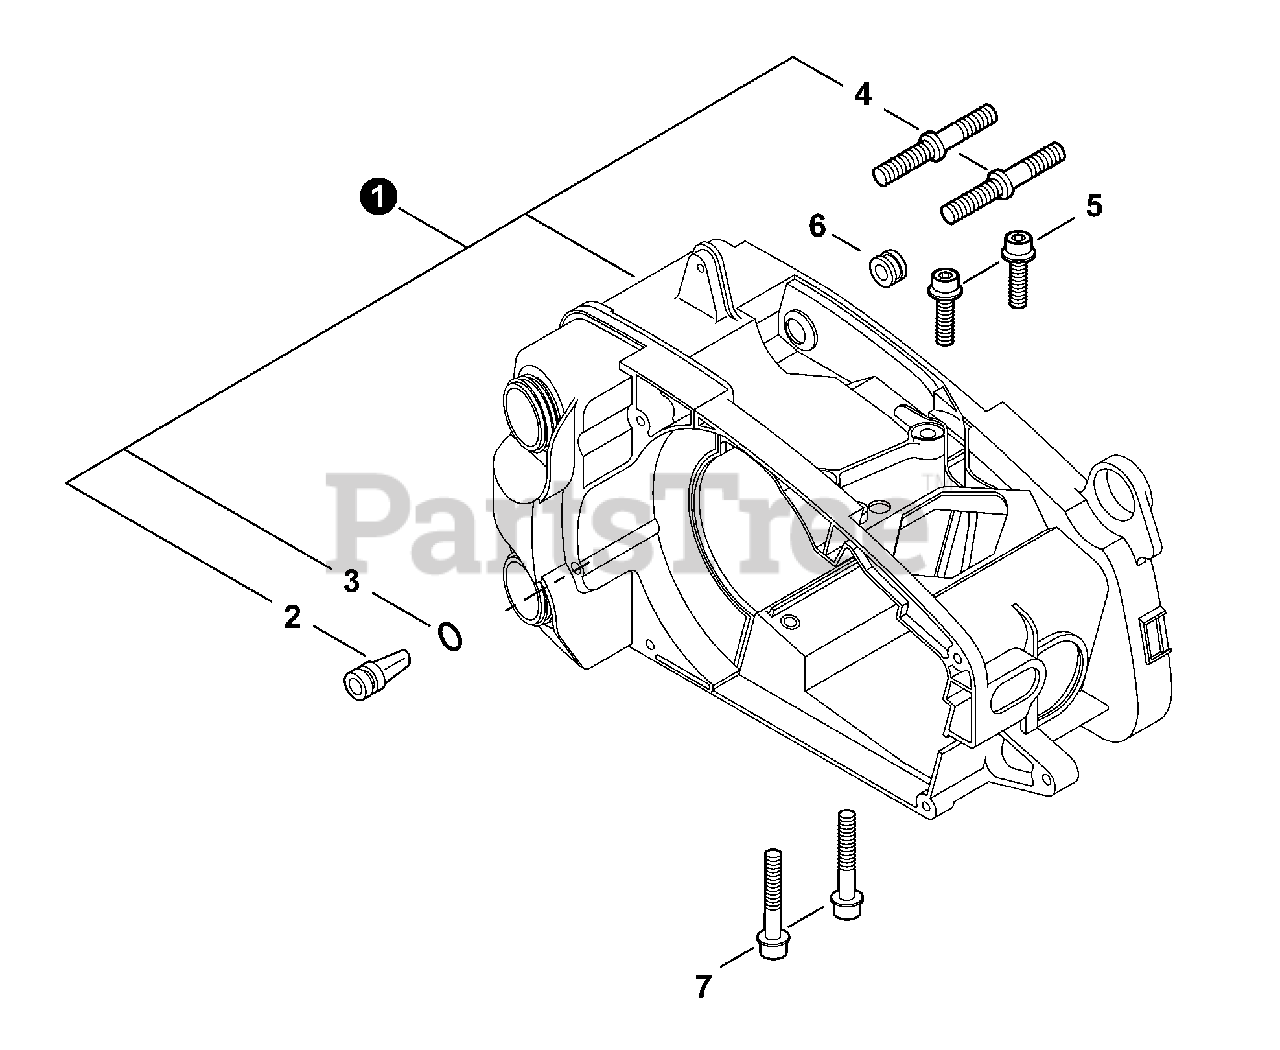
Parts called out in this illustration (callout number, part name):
1	COVER ASSY, ENGINE - ORANGE
2	VENT ASSY
3	O-RING S-4
4	BOLT, STUD 6
5	BOLT 5×20
7	BOLT 5×30
